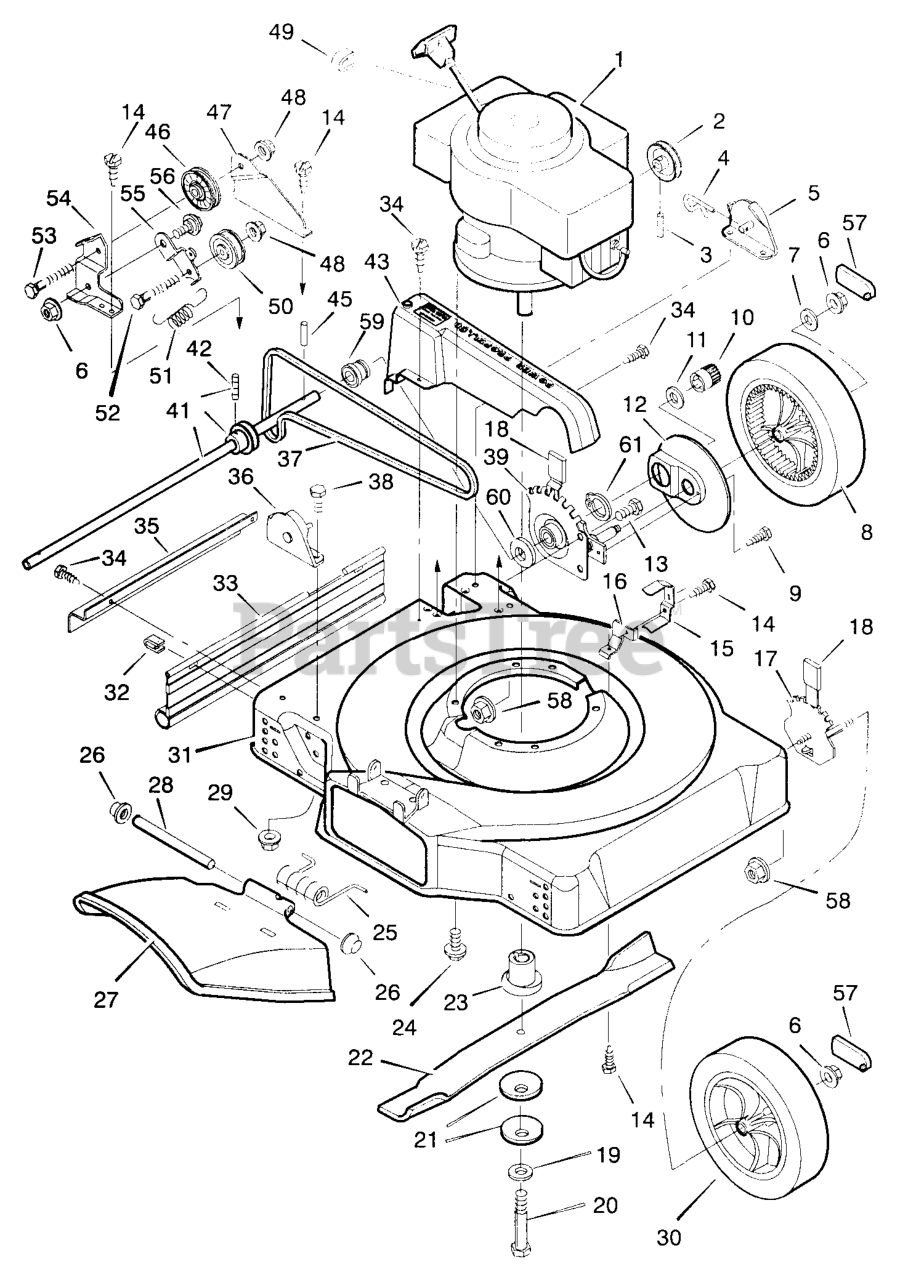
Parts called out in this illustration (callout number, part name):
1	Engine *
3	Pin, Spring
4	Pin, Hair
5	Bracket, Left Handle
6	Nut
7	Washer
8	Wheel, Drive
10	Gear, Right Pinion
12	Cover, Dust
13	Bolt, Hex
15	Guide, Belt
16	Belt Guide, Briggs
17	Height Adjuster, Front
21	Washer, Belleville
23	Adapter, Blade
24	Bolt, Engine
25	Spring, Torsion
26	Push On Cap
27	Deflector, Chute
29	Nut
30	Wheel and Tire, Front
31	Housing
32	Retainer
33	Deflector, Rear
35	Guard, Axle
36	Bracket, Right Handle
37	Belt, Briggs & Stratton
39	Height Adjuster, Left
41	Axle, Pulley & Setscrew
42	Setscrew
43	Belt Guard, Briggs
45	Pin, Drive
46	Pulley, Idler
47	Support, Idler
48	Nut
49	Stop, Rope
50	Pulley, Idler
51	Spring, Extension
52	Bolt, Hex
53	Bolt, Hex
54	Bracket, Idler
55	Arm, Idler
56	Bolt, Shoulder
57	Cap, Hub
58	Nut, Flange
59	Bearing and Retainer
60	Washer, Belleville
61	Retainer Ring
